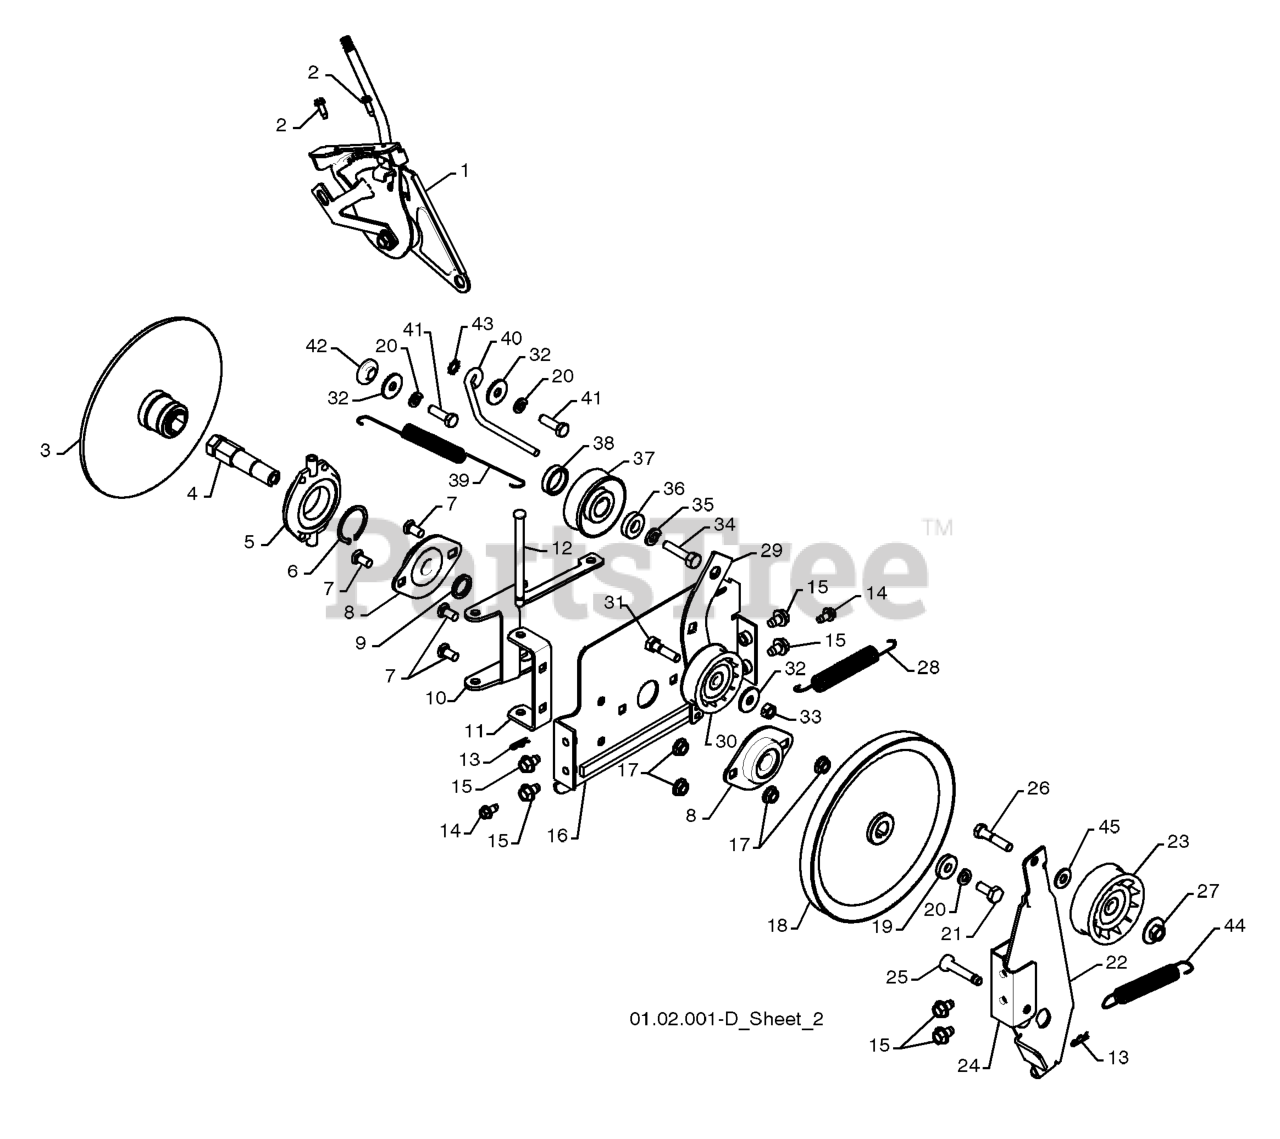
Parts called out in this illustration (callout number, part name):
1	HEAD ASSY SPEED
2	SCREW #10-24 X 5/8
3	DRIVE PLATE WELDMENT
4	SHAFT.HEX.SHORT
5	TRUNNION BEARING ASSY
6	RETAINING RING (2 2)(3 2)
7	BOLT
8	BEARING FLANGE
9	SPACER, BEARING
10	LEVER.SHIFTER.PLATE.BLACK
11	BRACKET, SHIFTER SUPPORT
12	PIN, PIVOT LEVER
13	RETAINER CLIP PM
14	SCREW
15	BOLT 5/16-18 X .500
16	PLATE.DRIVE.MOUNTING.BLACK
17	NUT.FLANGE.5/16
18	PULLEY.TRACTION.7.75
19	WASHER, FLAT
20	WASHER.LOCK.HVY.HLCL.SPR.5/16
21	SCREW 5/16-18 X .750
22	ARM.IDLER.BRAKE
23	PULLEY.W/SPACER.2.75
24	BRACKET, IDLER PIVOT
25	PIN, IDLER PIVOT
26	HEX BOLT
27	LOCKNUT 5/16-18
28	RP SPRING, TRACTION IDLER
29	ARM, IDLER
30	PULLEY.W/SPACER.2.25
31	BOLT.5/16-18X1-1/4 FULL.THREAD
32	STEEL WASHER
33	NUT.CENTERLOCK.5/16-
34	SCREW, HEX HD 3/8-24 X 1-3/8
35	LOCKWASHER
36	WASHER, FLAT 3/8
37	PULLEY,ENGINE TRACTION DRIVE
38	SPACER.ENGINE.PULLEY
39	SPRING.RETURN
40	BELT.GUIDE.RH
42	RP BUSHING, IDLER PIVOT
43	WASHER EXT TOOTH LOCK 5/16
44	SPRING, BRAKE
45	WASHER.20X8.5
